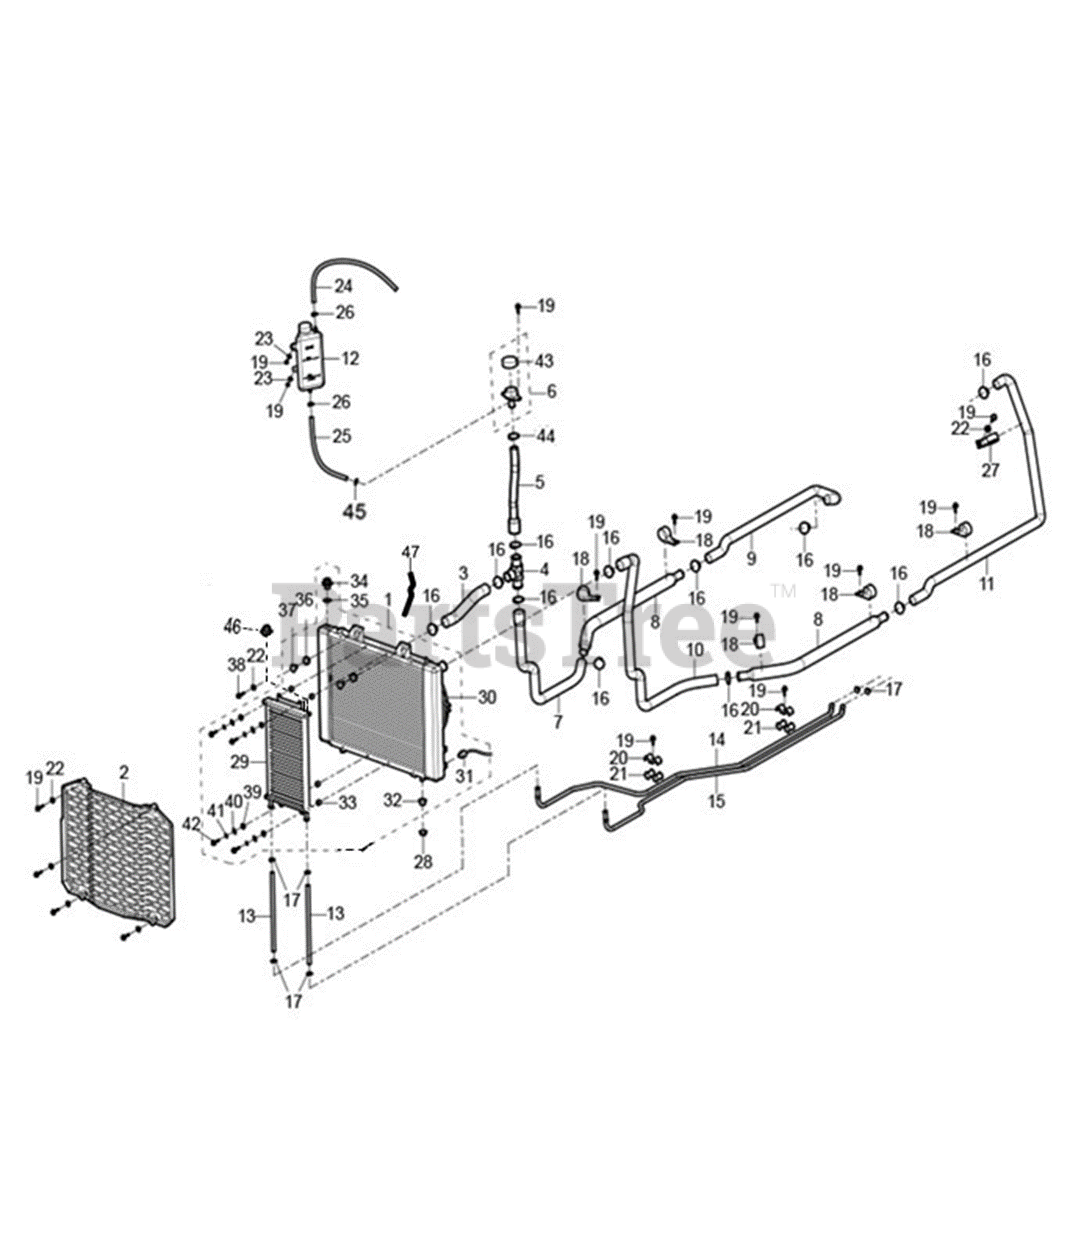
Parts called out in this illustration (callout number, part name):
2	RADIATOR COVER
3	HOSE - WATER INLET - RADIATOR
4	TEE PIPE COUPLING
5	RADIATOR WATER INLET HOSE IV
6	FILTER NECK
7	RADIATOR HOSE WATER INLET
8	HOSE - ALUMINIUM I
9	RADIATOR HOSE WATER INLET I
10	RAD HOSE OUTLET II
11	RADIATOR HOSE WATER OUTLET I
12	TANK SURGE ASSEMBLY
13	HOSE - RUBBER I
14	METAL HOSE II
15	METAL HOSE I
17	LOCK CLAMP A
18	WATER PIPE CLAMP
19	HEXAGON FLANGE BOLT M6X16
20	FIXED PIPE CLAMPS M-SHAPED
21	RUBBER FUEL LINE
22	HEX FLANG NUT M6
23	FLANGE BUSHING
24	COOLANT HOSE
25	RUBBER HOSE W/INNER SPRING 5X9
27	CLIP - WATER HOSE II
29	OIL COOLER
30	WATER TANK (CHALLENGER 750)
31	WATER TEMPERATURE SENSOR
33	WATER TANK CUSHION
35	O-RING 9X1.8
36	WATER TANK BRACKET RING
37	WATER TANK BRACKET BUSHING
38	HEXAGON FLANGE BOLT M6X25
39	HEXAGON FLANGE HEAD NUT M6
40	PLAIN WASHER M6
41	SPRING WASHER 6
42	HEX BOLT M6X25
43	WATER TANK COVER
44	HOSE CLAMP
45	SPRING CLAMP C
46	PRESSURE SENSOR
46	OIL PRESSURE SWITCH KIT
47	GROUND WIRE
48	O-RING 9 x 2
